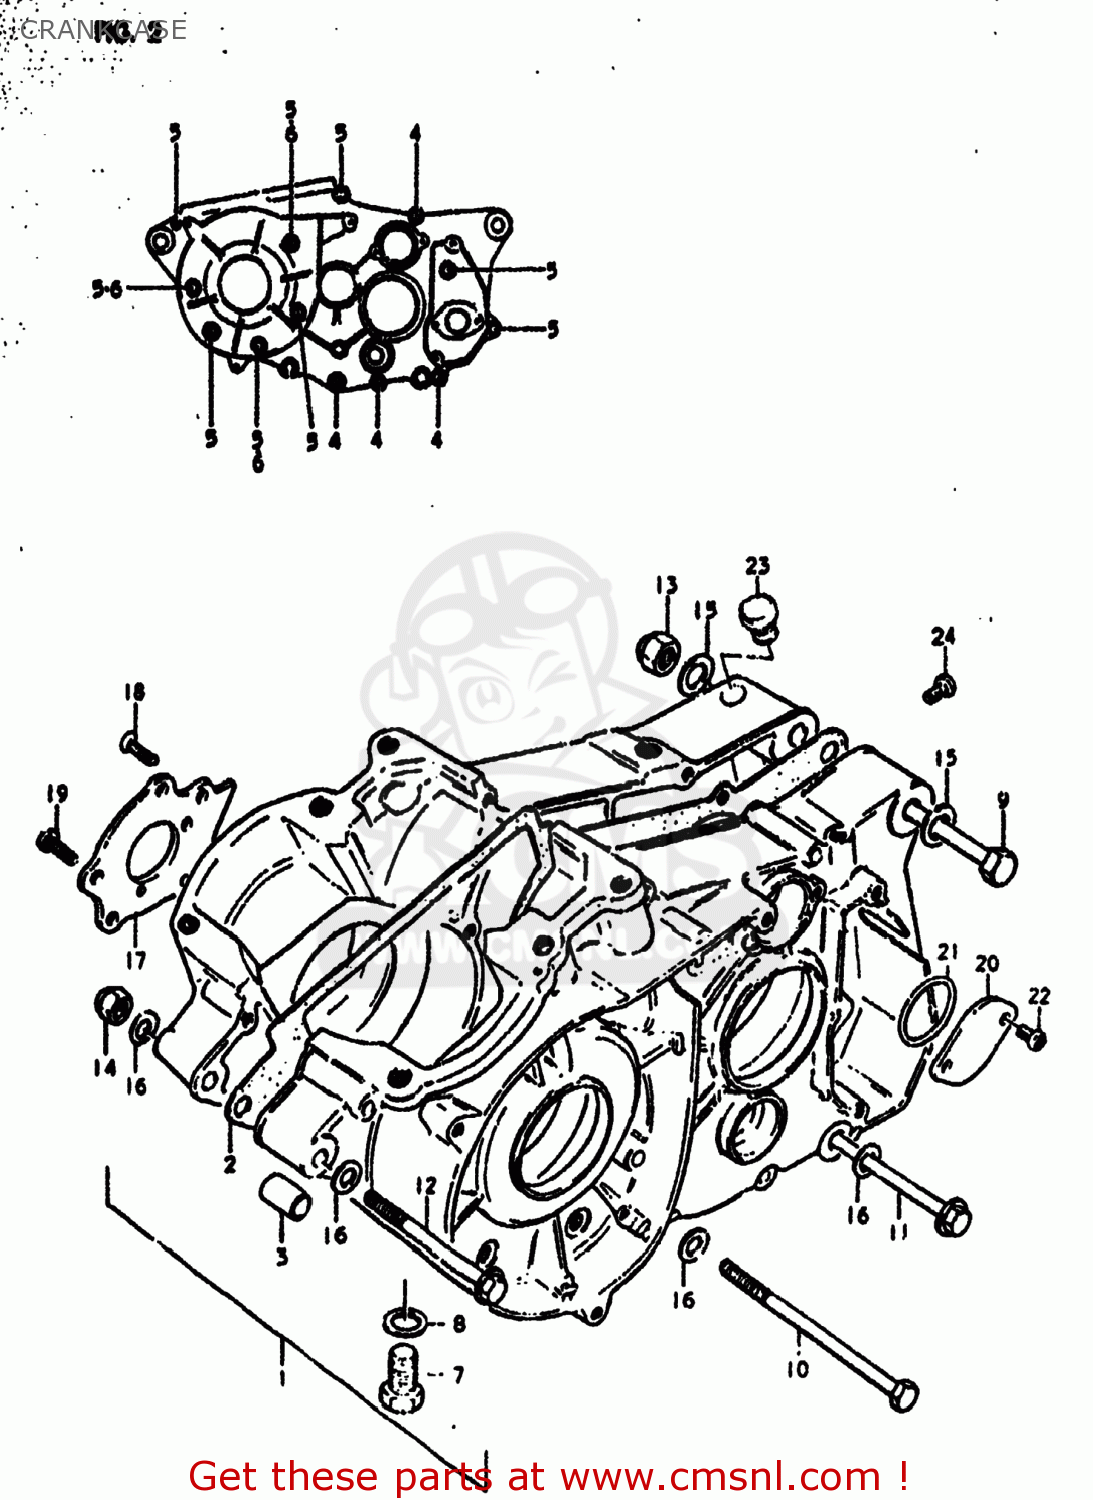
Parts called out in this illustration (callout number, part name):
1	CRANKCASE SET
2	GASKET,CRANKCASE (MCA)
3	PIN
4	SCREW 6X65
5	SCREW (6X45)
6	WASHER 6MM
7	PLUG
8	GASKET(14X19.2X2) (NAS)
9	BOLT
10	BOLT(8X145)
11	BOLT
12	BOLT
13	NUT
14	NUT
15	WASHER
16	WASHER
17	PLATE,OIL RESERVOIR
18	SCREW
19	SCREW
20	CAP,GEAR SHIFT CAM PIVOT
21	O-RING (D:2.4 ID:26.2)
22	SCREW
23	Plug
24	SCREW,6X6
